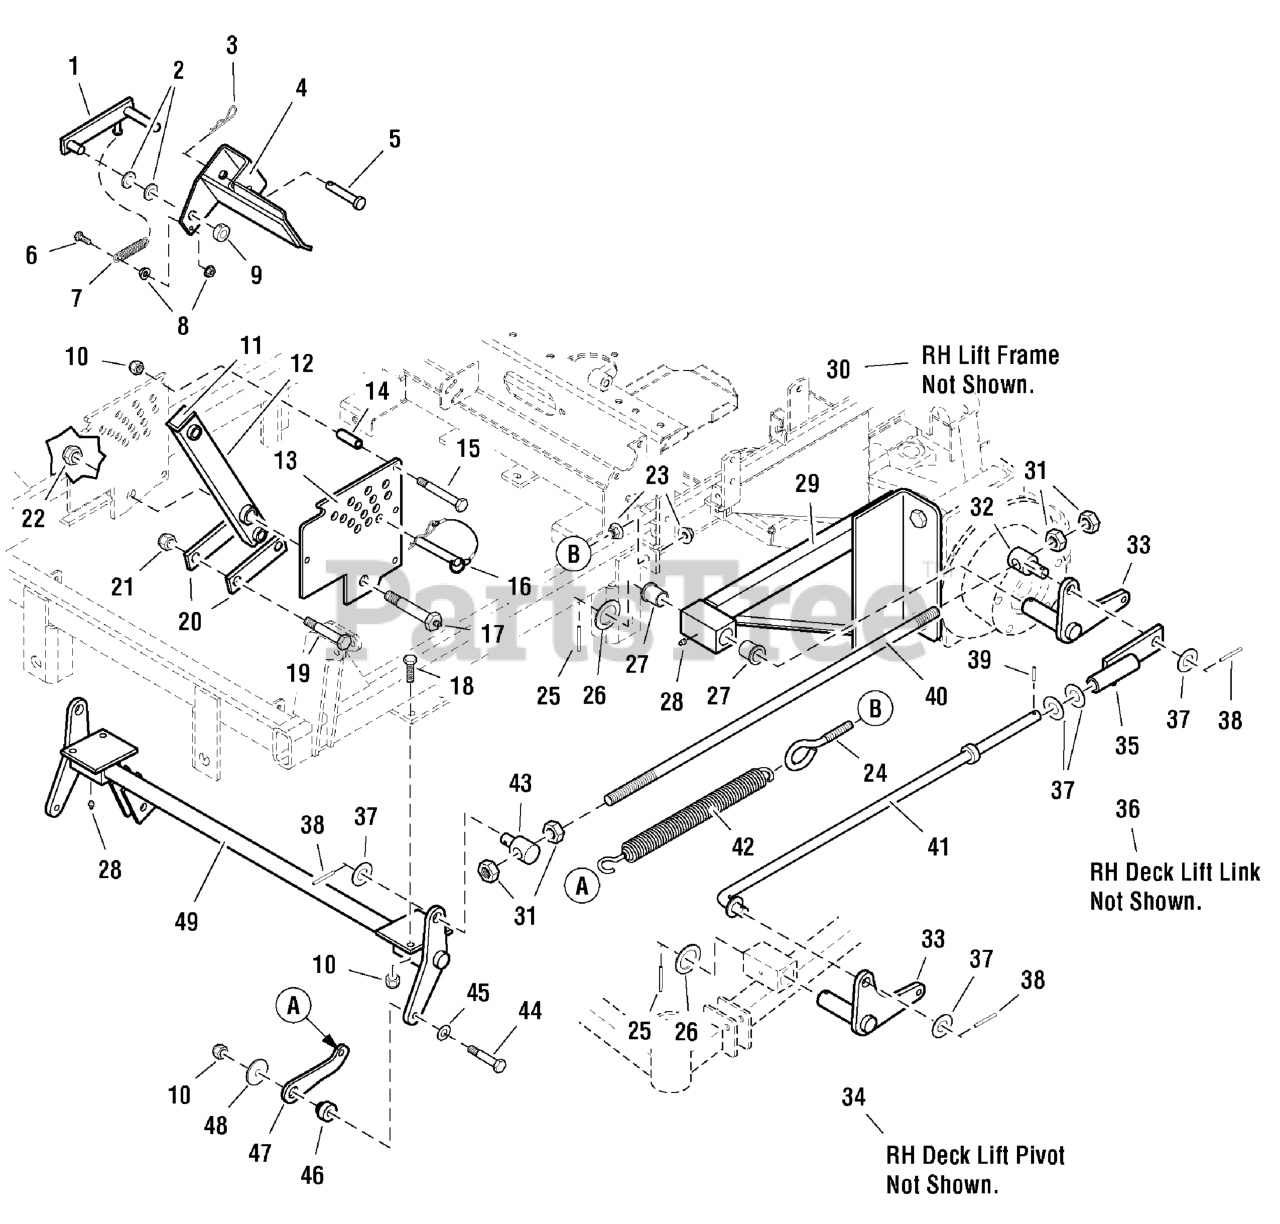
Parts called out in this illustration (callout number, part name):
1	DECK LIFT LOCK
2	WASHER, 1/2 SAE
3	HAIRPIN CLIP
4	WELD, DECK LIFT PEDAL
5	PIN, Clevis, 1/2 x 2-1/2
6	BOLT, 1/4-20 x 3/4
7	SPRING, Extension
8	NUT, 1/4-20 HEX SERR. FLANGE
9	COLLAR, Split, 1/2
10	NUT, 3/8-16 HEX NYLON LOCK
12	ARM, Deck Lift Pivot
13	DECK HEIGHT PLATE
14	SPACER, .38 x .50 x 1.56
15	BOLT, 3/8-16 X 2-3/4" GD5 CZ
16	PIN, 1/2 x 3-1/2 w/ Lanyard
17	LIFT PIVOT BOLT
18	BOLT, 3/8-16 X 1-1/4" GD5 CZ
19	BOLT, 1/2-20 x 3
20	DECK LIFT LINK
21	NUT, Hex, Nylon Lock, 1/2-20
22	NUT, 5/8-11 Hex Jam Nylon Lock
23	NUT, 3/8-16 Hex Serrated Flange
24	EYE BOLT, 3/8-16 X 2.96, 1.25THRD, .7EYE
25	PIN, Roll, 3/16 x 1-1/2
26	SHIM, 1.0 X 1.5 X 0.125
27	BUSHING, Flange
28	GREASE FITTING
29	ASSM, LIFT FRAME, LH
31	NUT, 5/8-11 Hex
32	SPRING ROD PIVOT
33	DECK LIFT PIVOT - LH
35	DECK LIFT LINK - LH
37	WASHER, 5/8" SAE
38	PIN, Spring, 3/16 x 1-1/4
39	PIN, Roll, 3/16 x 3/4
40	DECK ADJUSTMENT ROD
41	DECK LIFT ROD
42	DECK LIFT SPRING
43	SPRING ROD PIVOT
44	BOLT, 3/8-16 X 2, GD5, CZ
45	WASHER, 3/8 SAE
46	DECK PIVOT BUSHING
47	SPRING LINK
48	WASHER, 3/8 x 2
49	DECK LIFT SHAFT & MOUNT ASSEMBLY
